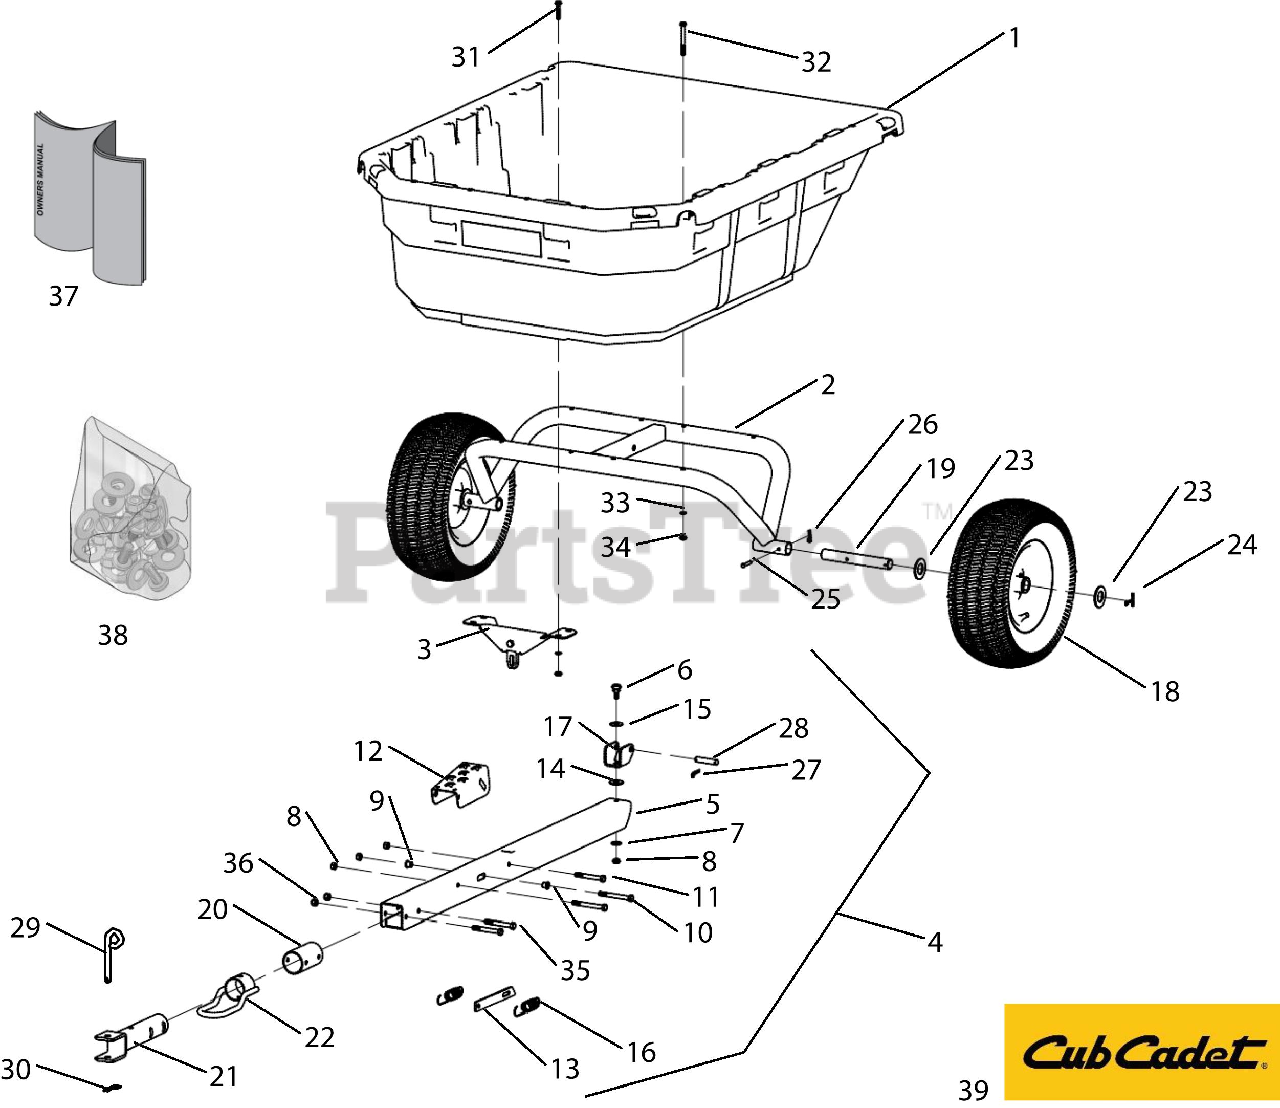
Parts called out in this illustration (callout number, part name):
2	Undercarriage
3	Front Support
4	Drawbar Assembly
5	Drawbar
6	Shoulder Bolt
7	Washer 3/8" Uss
8	Hex Nut 3/8-16 C-Lock
10	Hex Bolt 3/8-16 X 3-1/2"
11	Hex Bolt 3.8-16 X 3"
14	Washer 1/2" Uss
15	Spring Washer
16	Latch Spring
17	Swivel Clevis
19	Stub Axle
20	Hitch Bushing
21	Hybrid Hitch
22	Hitch Keeper
23	1" Sae Flat Washer
24	Cotter Pin 3/16" X 1-1/2"
25	Clevis Pin 1/4" X 1-1/2"
26	Hairpin Cotter 1-3/16"
27	Hairpin Cotter 1-9/16"
28	Pin 1/2" X 2-13/32"
30	Cotter Hairpin
31	5/16-18 X 1-1/2" Hex Bolt
32	5/16-18 X 3" Hex Bolt
33	5/16" Split Lock Washer
34	5/16-18 Hex Nut
35	3/8-16 X 3" Hex Bolt
36	3/8-16 Nyloc Nut
37	Manual
38	Hardware Bolt Bag
39	Decal
